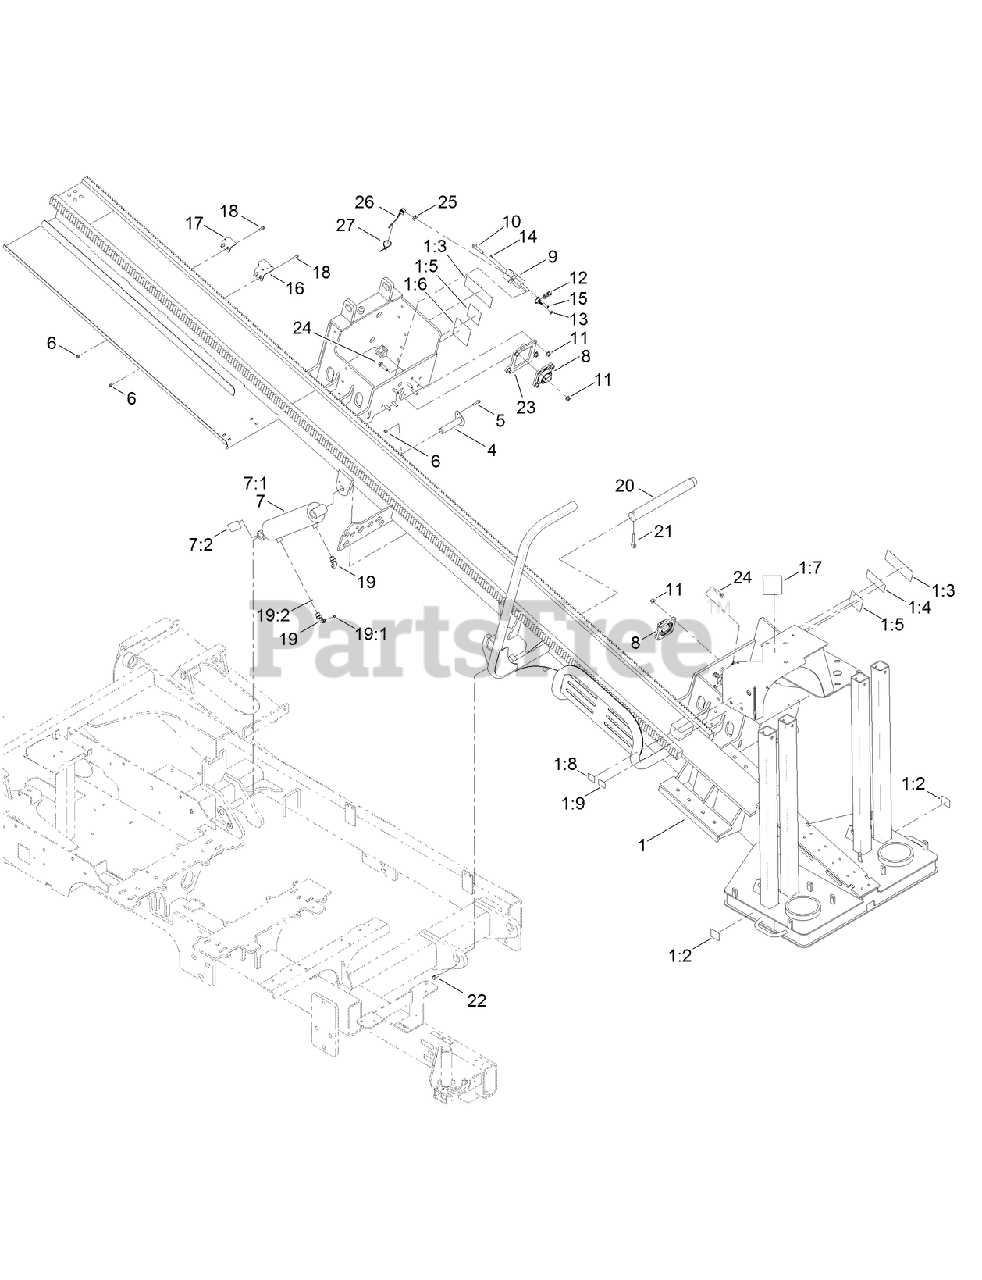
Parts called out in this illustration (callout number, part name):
1	THRUST FRAME ASM
1:2	DECAL-TIE DOWN
1:3	DECAL-DANGER, HAZARDOUS AREA
1:4	DECAL-WARNING, HYDRAULIC PRESSURE
1:5	DECAL-WARNING, CRUSHING
1:6	DECAL-SHOCK DANGER
1:7	DECAL-STAKEDOWN SET UP
1:8	DECAL-PIPE RETURN, CLEAR
1:9	DECAL-PIPE BREAKOUT, CLEAR
4	PIN-PIVOT
5	SCREW-HHF
6	NUT-LOCK, HHF
7	LIFT CYLINDER ASM
7:1	HYD CYLINDER ASM
7:2	DECAL-CAUTION, CYLINDER LOCK
8	BEARING-FLANGED Y, SQUARE
9	BRACKET-SENSOR, CAM
10	SCREW-HHF
11	NUT-LOCK, HHF
12	SENSOR-ROTARY
13	NUT-HEX
14	SCREW-HH
15	NUT-HHF
16	PLATE-MOUNT, PROXIMITY SWITCH
17	PLATE-MOUNT, SWITCH
18	SCREW-HHF
19	FITTING-ELBOW 90
19:1	O-RING
19:2	O-RING
20	PIN-PIVOT, MAIN
21	PIN-RETAINER
22	SCREW-HHF
23	PLATE-SUPPORT, BEARING
24	SCREW-HHF
25	CLIP-CONNECTOR
26	HARNESS-ADAPTOR, SENSOR
27	TIE-CABLE
